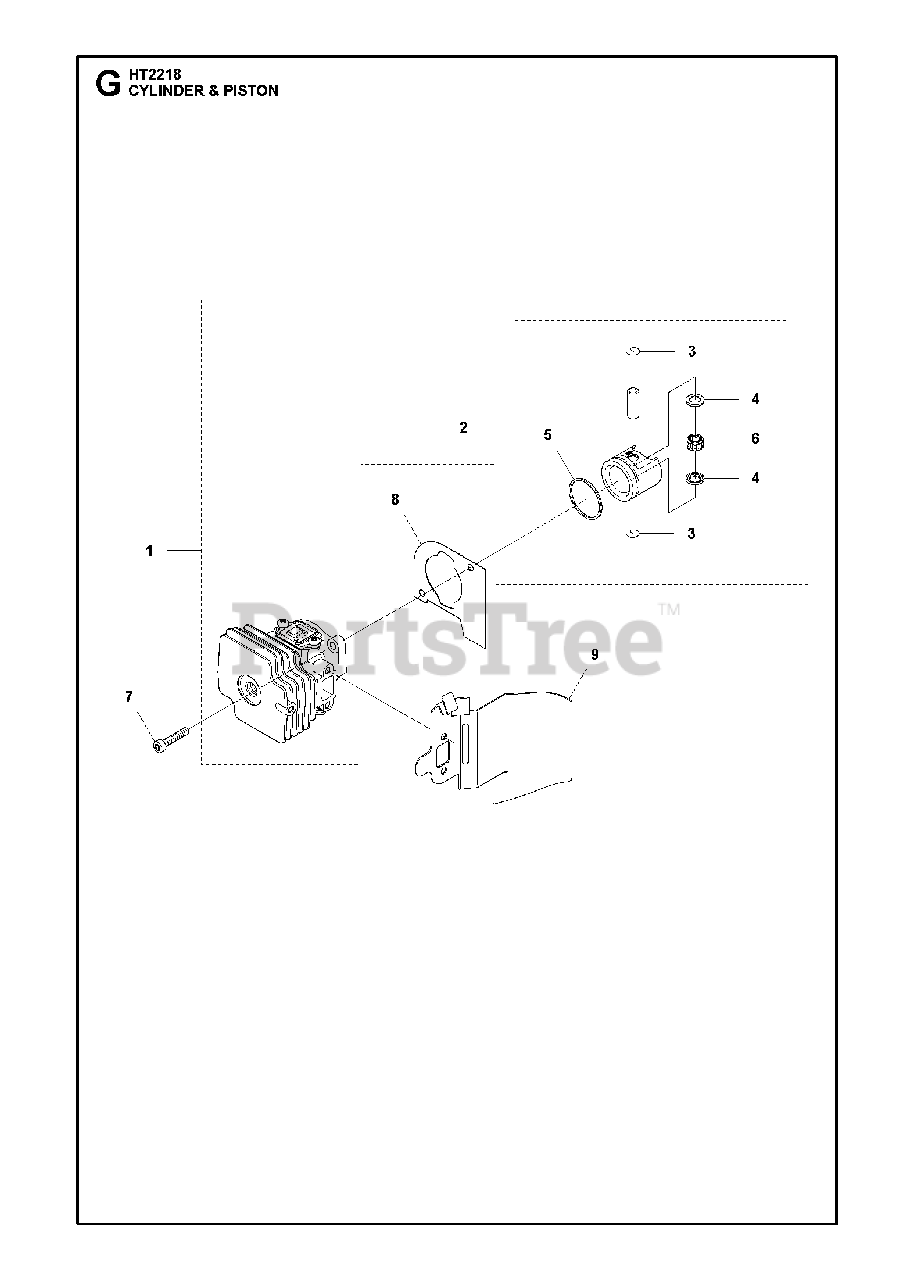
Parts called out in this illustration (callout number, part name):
2	PISTON ASSY.
3	CLIP RING
4	WASHER
5	PISTON RING
6	NEEDLE BEARING
8	GASKET CYLINDER
9	HEAT DEFLECTOR
